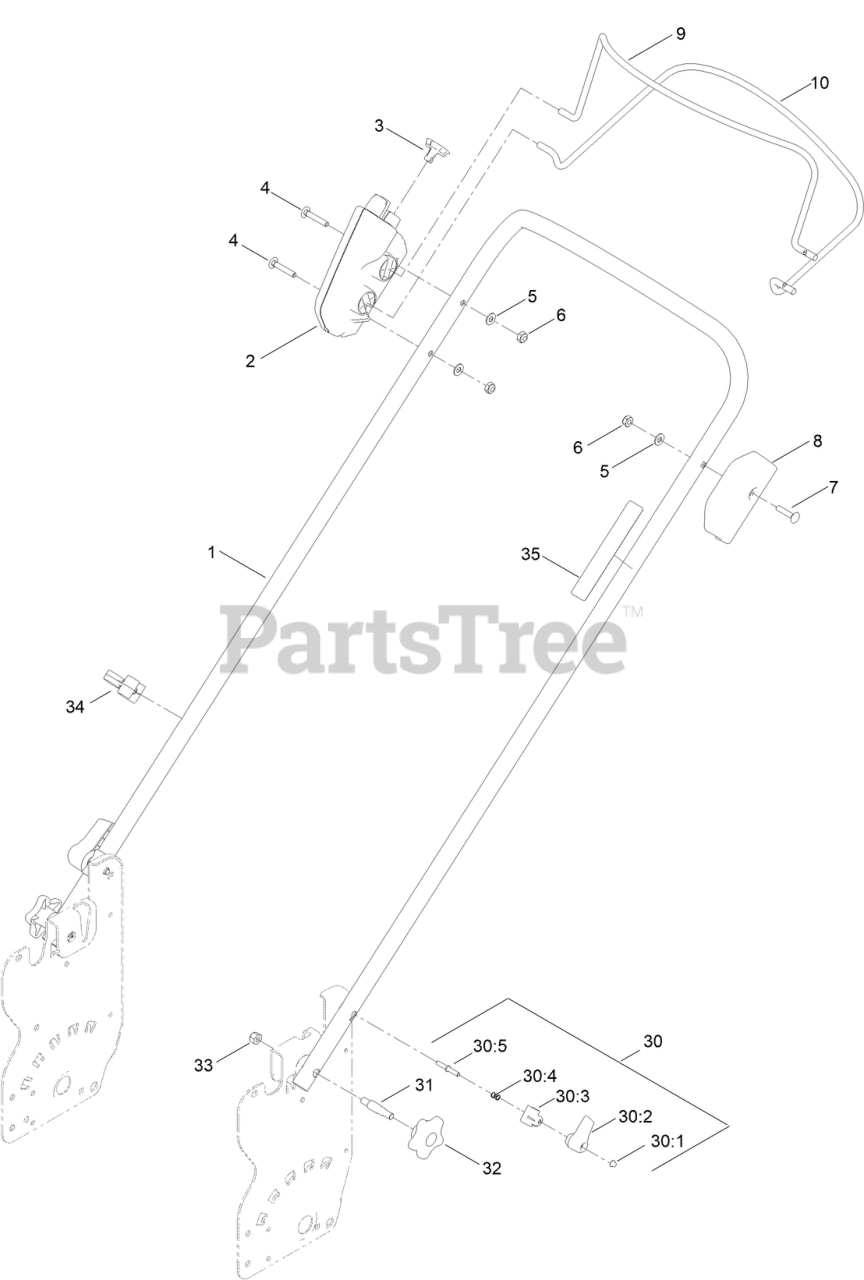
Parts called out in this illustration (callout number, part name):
1	HANDLE-MOWER, ELECTRIC
2	ASM-CONTROL, 2 BAIL
3	KEY-BAIL
4	SCREW-CARR
5	WASHER-FLAT
6	NUT-LOCK
7	SCREW-CARR
8	BASE-PIVOT
9	BAIL-BLADE
10	BAIL-TRACTION
30	QUICK RELEASE ASM
30:1	NUT-PUSH
30:2	LEVER-RELEASE
30:3	ANCHOR-SPRING
30:4	SPRING-COMPRESSION
30:5	ROD-RELEASE
31	BOLT-SHOULDER, HANDLE
32	KNOB-HANDLE
33	NUT-LOCK, NI
34	GUIDE-CABLE
35	DECAL-CONTROLS (60V START)
